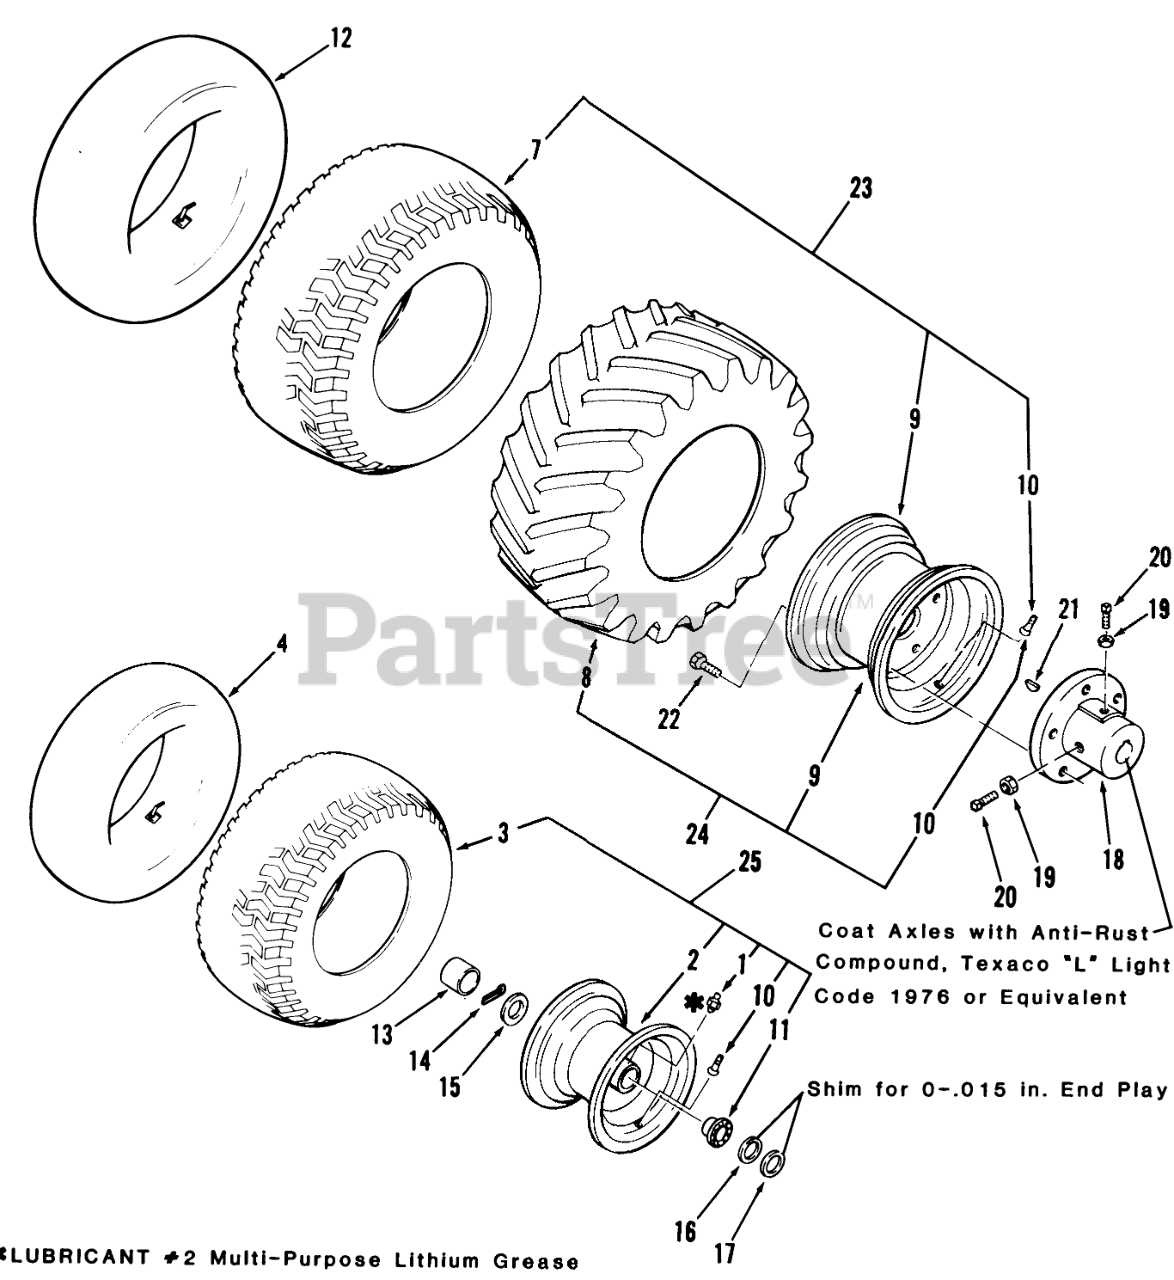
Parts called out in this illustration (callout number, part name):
1	Zerk
2	Front Wheel (includes Item 1, 10, 11)
3	TIRE TURF SAVER 16X6.50-8
4	TUBE-INNER
7	Tire
7	TIRE 9.50 X 12
7	Rear Tire 23 x 10.50-12 GT-1800 Only
8	Tire-Cleat, Rear
9	Wheel
9	WHEEL
10	VALVE
11	Ball Bearing
12	TUBE-INNER
13	HUB CAP-FLAT BLACK
14	COTTER PIN-4
15	WASHER-WHEEL
16	WASHER
17	WASHER-SHIM
18	Hub Rear
19	Nut
20	Screw-Set
21	KEY-WOODRUFF
22	Lug Nut
23	Wheel and Tire
23	Engine
23	Rear Wheel and Tire Assembly-Turf Twin Only
24	Right Rear Wheel and Tire Assy-Cleat
24	Left Rear Wheel and Tire Assy-Cleat
25	ASSY-WHEEL & TIRE
